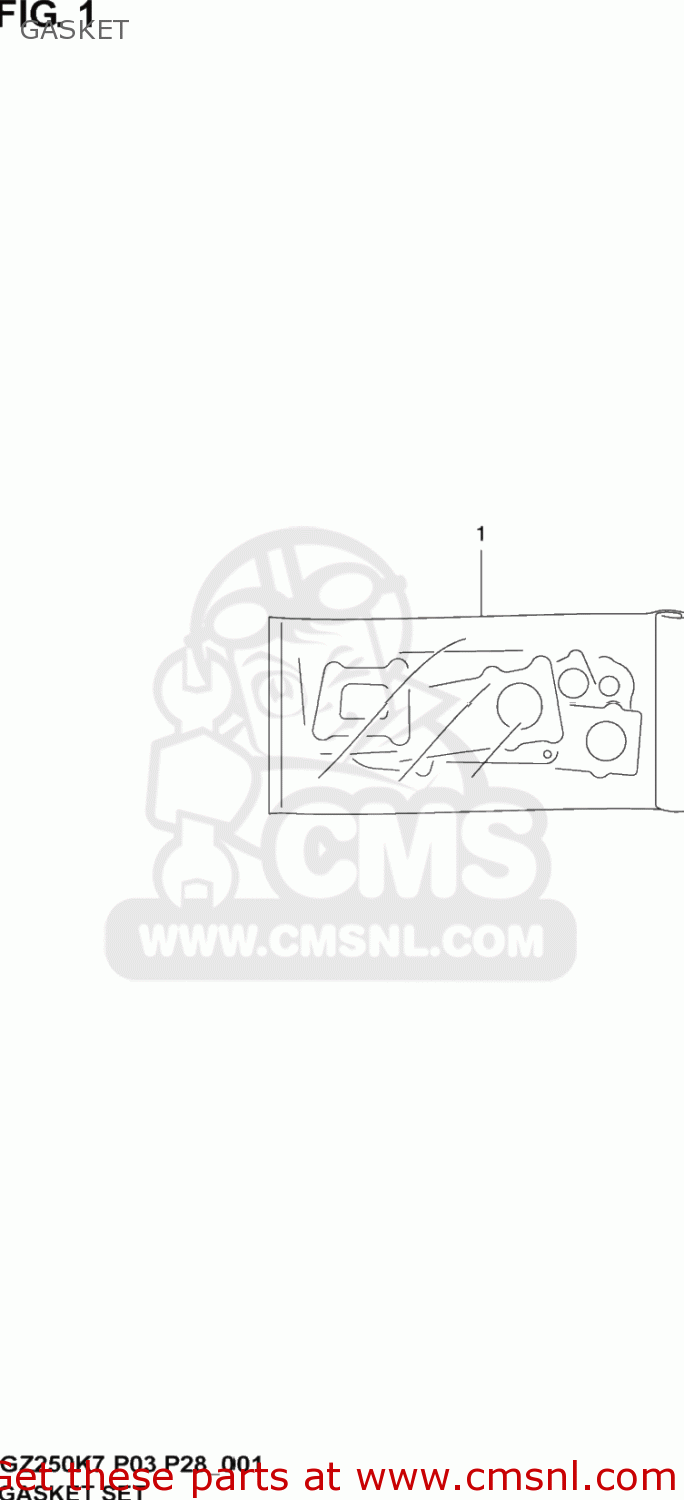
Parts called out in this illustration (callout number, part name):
1	GASKET SET (NAS)
2	GASKET,CYLINDER HEAD (NAS)
3	GASKET,CYLINDER (NAS)
4	GASKET,CLUTCH COVER (NAS)
5	GASKET,MAGNETO COVER (NAS)
6	GASKET,TENSIONER ADJUSTER (NAS)
7	GASKET,EXHAUST PIPE (NAS)
8	O RING(D:1.9,ID:8.6)
9	O RING(D:2.4,ID:15.8)
10	O RING(D:2.5,ID:21)
11	O RING(D:2.4,ID:26.2)
12	O RING(D:2.4,ID:39.7)
13	O RING(D:2.4,ID:23)
14	O RING(D:2.4,ID:73)
15	O RING(D:2.4,ID:85)
